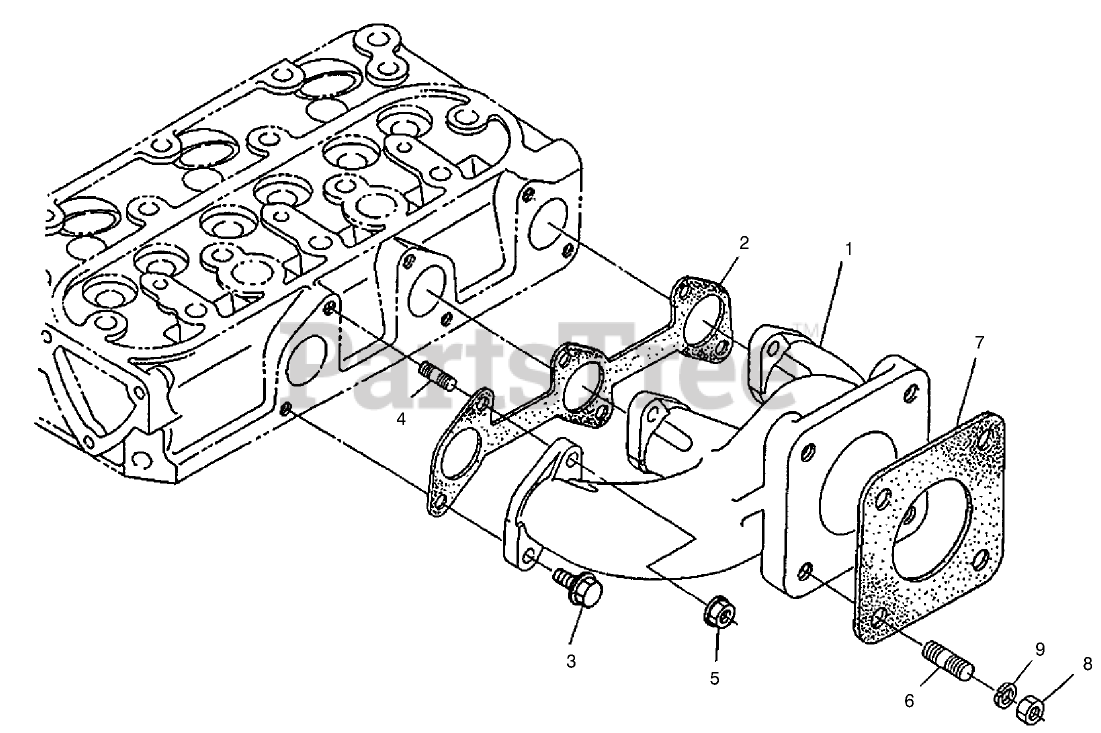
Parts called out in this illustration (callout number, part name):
1	MANIFOLD, EXHAUST
2	Gasket (Thru Aug. 1994)
2	GASKET
4	STUD
7	GASKET-MUFFLER
9	WASHER-SPRING
